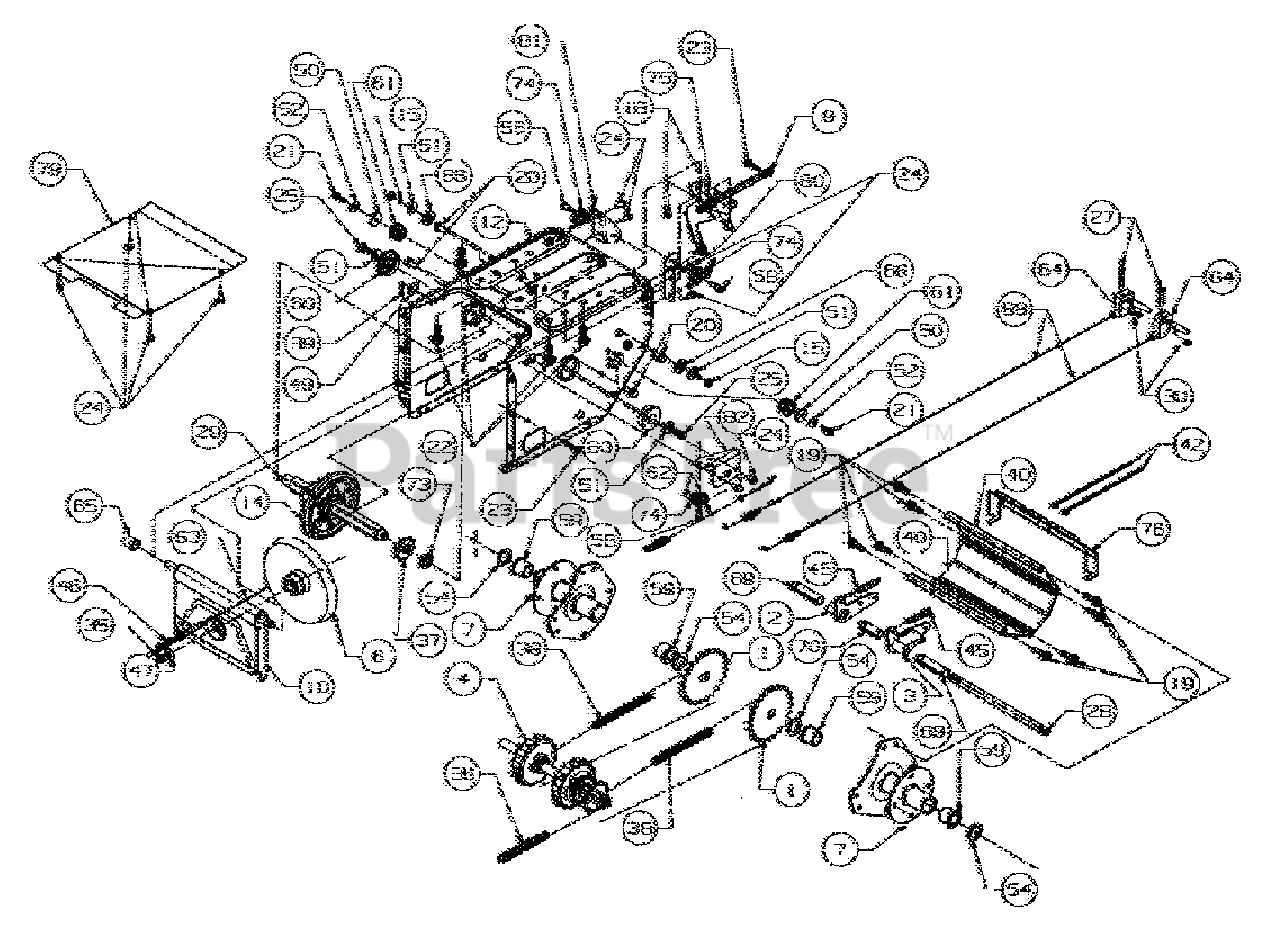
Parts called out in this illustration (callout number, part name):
1	Axle Assembly
2	Dog Assembly-R.H.
3	Dog Assembly-L.H.
4	Shaft Assembly
6	Disc Assembly
14	Wheel Assembly Friction
20	Screw
30	Nut Flange
39	Pin Cotter
40	Housing Track
42	Cable Tie
45	Spring
46	Spring
47	Washer-Bell
49	Washer-Flat
50	Washer-Flat
51	Washer-Bell
52	Washer-Bell
54	Washer-Flat
56	Lubricant
58	Screw-Shoulder
59	Bearing-Flange
60	Bearing-Ball
61	Bearing-Hex Flange
62	Cable-Auger Clutch
63	Cable-Drive Clutch
64	Trigger Lever
66	Spacer-Shoulder
69	Spacer-Split
70	Spacer-Split
73	Spacer
74	Roller-Cable
